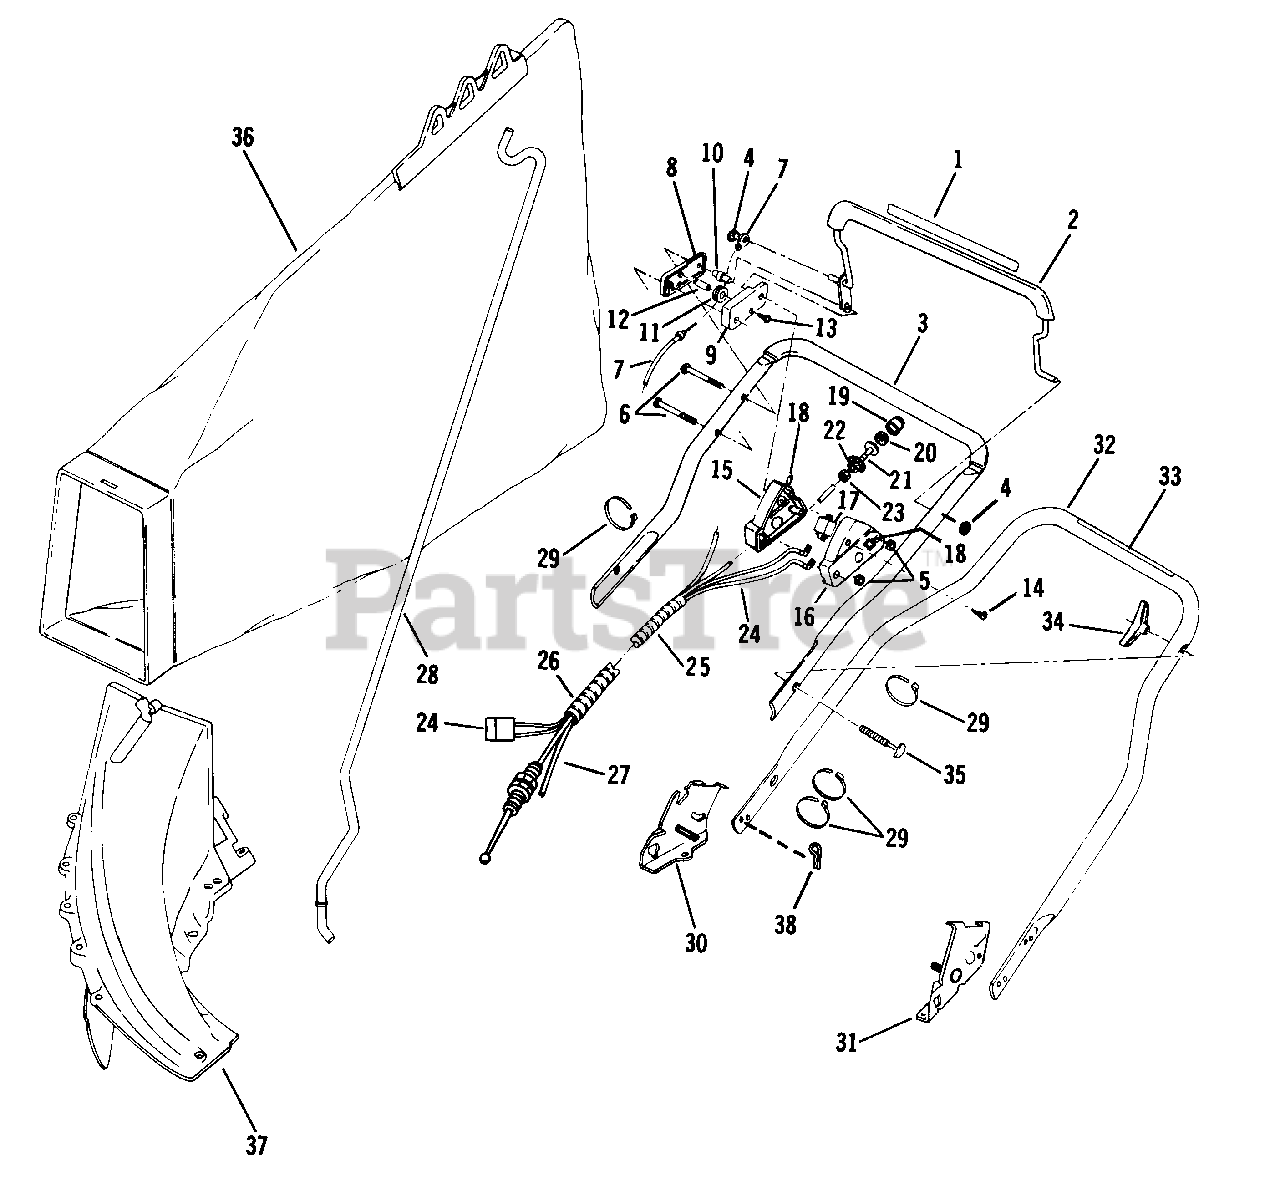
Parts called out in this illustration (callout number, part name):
1	Decal-Blade Control
2	Control Lever Assembly
3	Top Handle and Grip Assembly
4	Pushnut
5	Nut-Hex-Centerlock
7	Control Cable Assembly
8	Control Case-Outer
9	Control Case-Inner
11	Pulley
15	Console-R.H.
16	Console-L.H.
17	Switch Assembly
19	Primer Bulb
21	Primer Base
23	Locknut
24	Wire Harness Assembly
25	Spiral Tubing
26	Spiral Tubing
27	Tubing-Primer
28	Rod-Grass Bag
29	Tie Strap
30	Handle Bracket-R.H.
31	Handle Bracket-L.H.
32	Handle-Bottom
33	Decal-Starting Inst.
35	Screw-Folding Handle
36	Bag Assembly
37	Chute Assembly
38	Hair Pin
